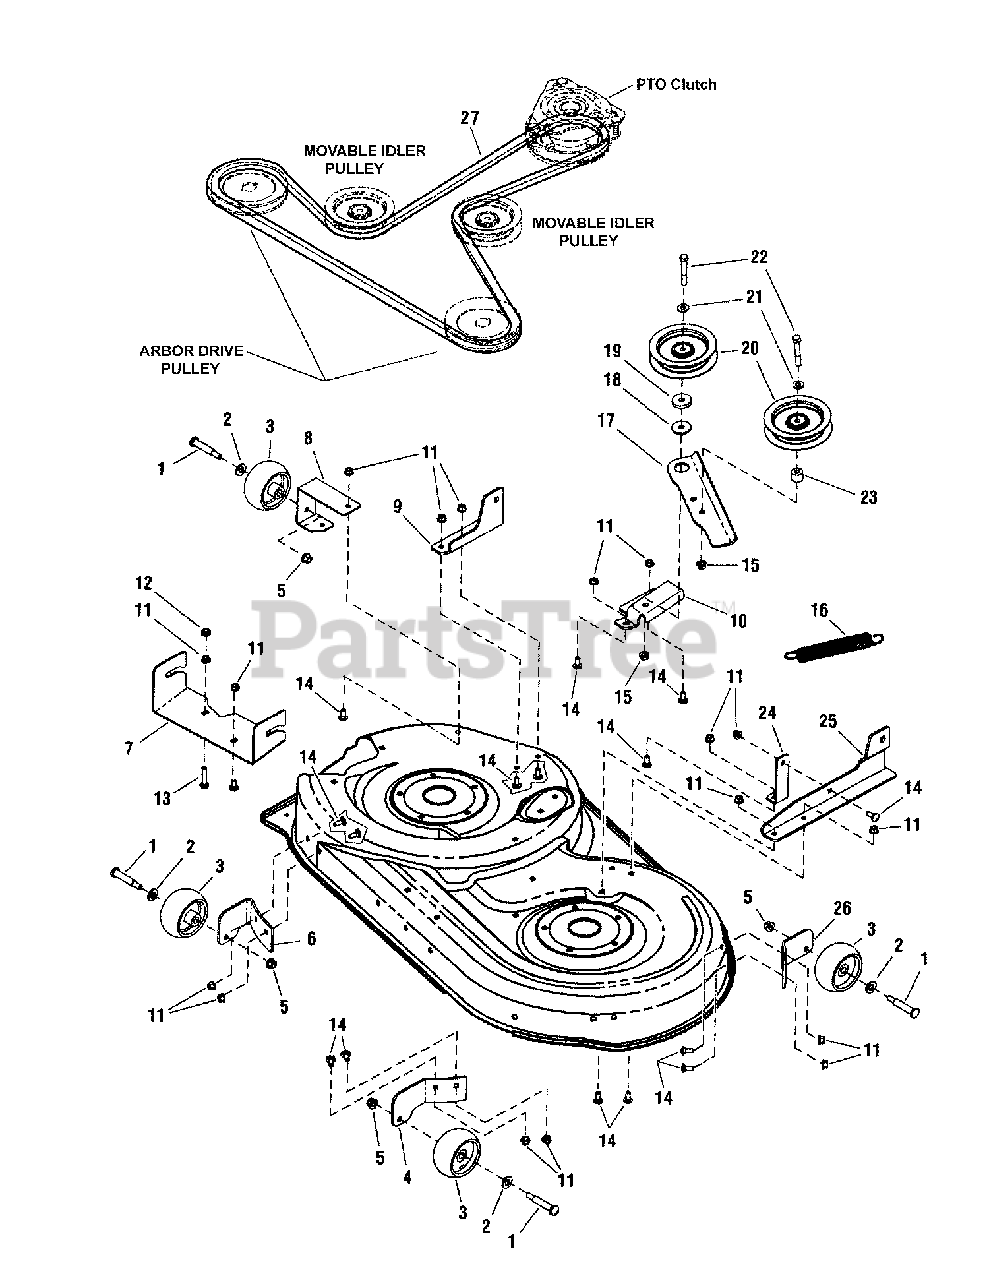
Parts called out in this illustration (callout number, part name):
1	BOLT, Shoulder (Gage Wheel) 3/8-16 x 2.781 x 3/4"
2	WASHER, .51 I.D. x 1.0 O.D. x .10 Thick
3	WHEEL, Gage (2" Wide, 3.92 Dia.)
4	BRACKET, Gage Wheel L.H. Front
5	NUT, 3/8-16 Hex Flange Nyloc
6	BRACKET, Gage Wheel R.H. Front
7	HITCH, Mower Front
8	BRACKET, Gage Wheel R.H. Rear
9	SUPPORT, Mower Rear R.H.
10	BRACKET, Fixed Idler
11	NUT, 5/16-18 Hex Flange Lock, Small - Black
12	NUT, 5/16-18 Hex Two-Way Lock
13	BOLT, 5/16-18 x 1-1/2" Round Head Square Neck, GR5
14	BOLT, 5/16-18 x 3/4" Round Head Short Square Neck, GR5
15	NUT, 3/8-16 Hex Flange Whizlock, GR F
16	SPRING, Extension
17	ARM, Idler
18	SPACER, .406 I.D. x 1.50 O.D. x .350 Thick, Powdered Metal
19	WASHER, 3/8 (.41 I.D. x 1.50 O.D. x .25 Thick)
20	PULLEY, Idler, 4" O.D. x .378 I.D. x 1"
21	WASHER, .3/8 (.41 I.D. x .87 O.D. x .08 Thick)
22	SCREW, 3/8-16 x 2-1/2" Hex Head Cap, GR5
23	SPACER (.390 x .900 x .70 Thick)
24	BRACE, Mower Support
25	SUPPORT, Mower Rear L.H.
26	BRACKET, Gage Wheel L.H. Rear
27	V-BELT, A Wedge 98.00 Effective Length, Belt Sect. HA
